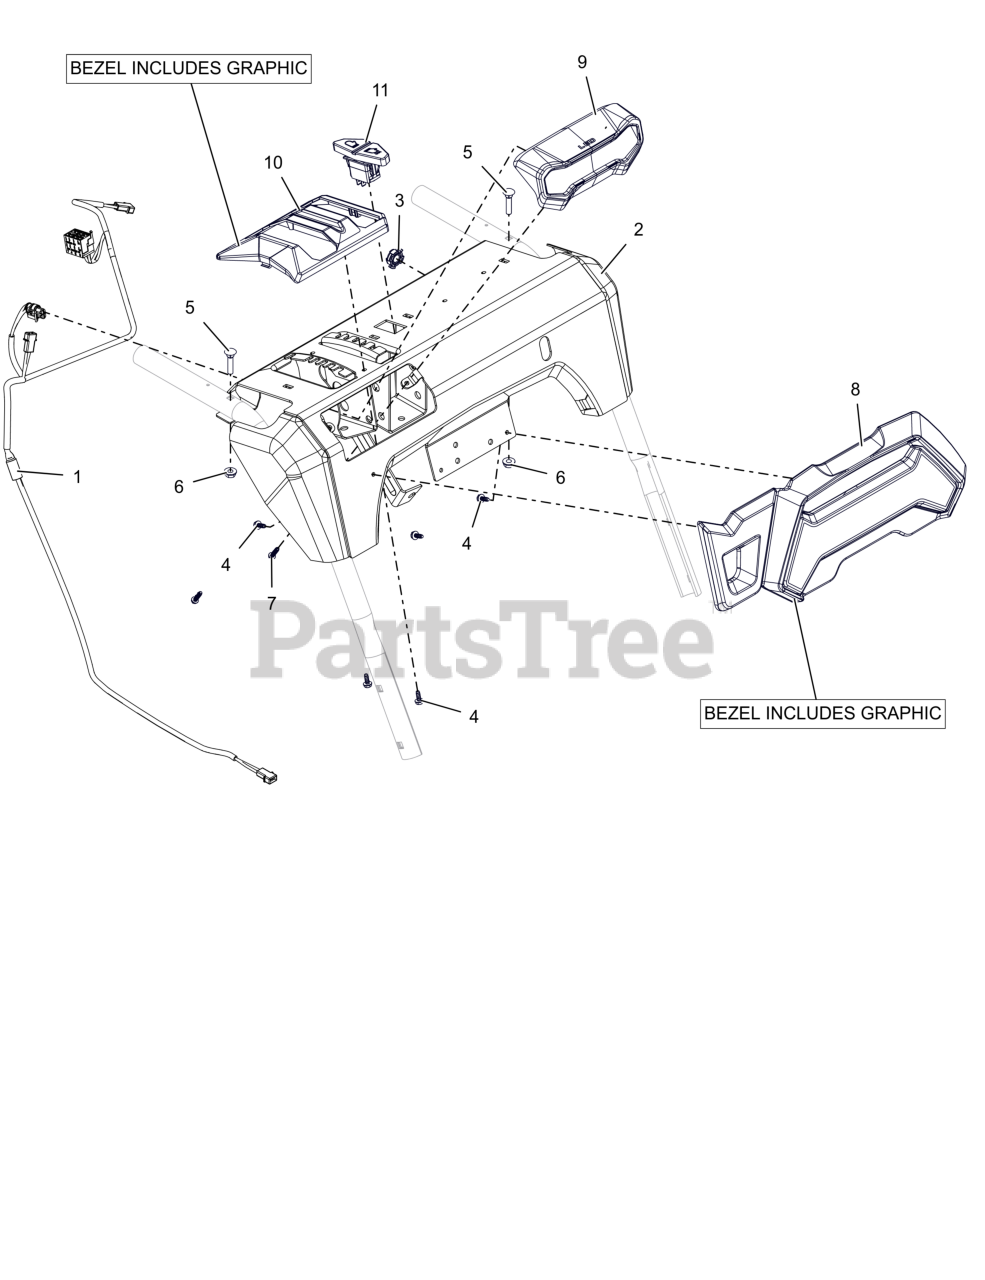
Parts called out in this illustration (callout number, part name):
1	HARNESS- WIRE - LT HG
2	PANEL, DASH-W/DECAL FRIC-ID
3	CRANK BUSHING, NYLON CHUTE BK
4	SCR, PLASTIC #10X.50
5	BLT-RDHDXLSQNK.25-20X1.25 G5ZC
6	NUT-LK-CTR-FLG .25-20 ZC120
7	SCR-HWH 10-16X.75 HI-LO ZCC
8	BEZEL, LARGE - DELUXE
9	HEADLIGHT ASM- LED
10	BEZEL, SHIFT - FRICTION
11	SWITCH- ROCKER SPST-ON/OFF
